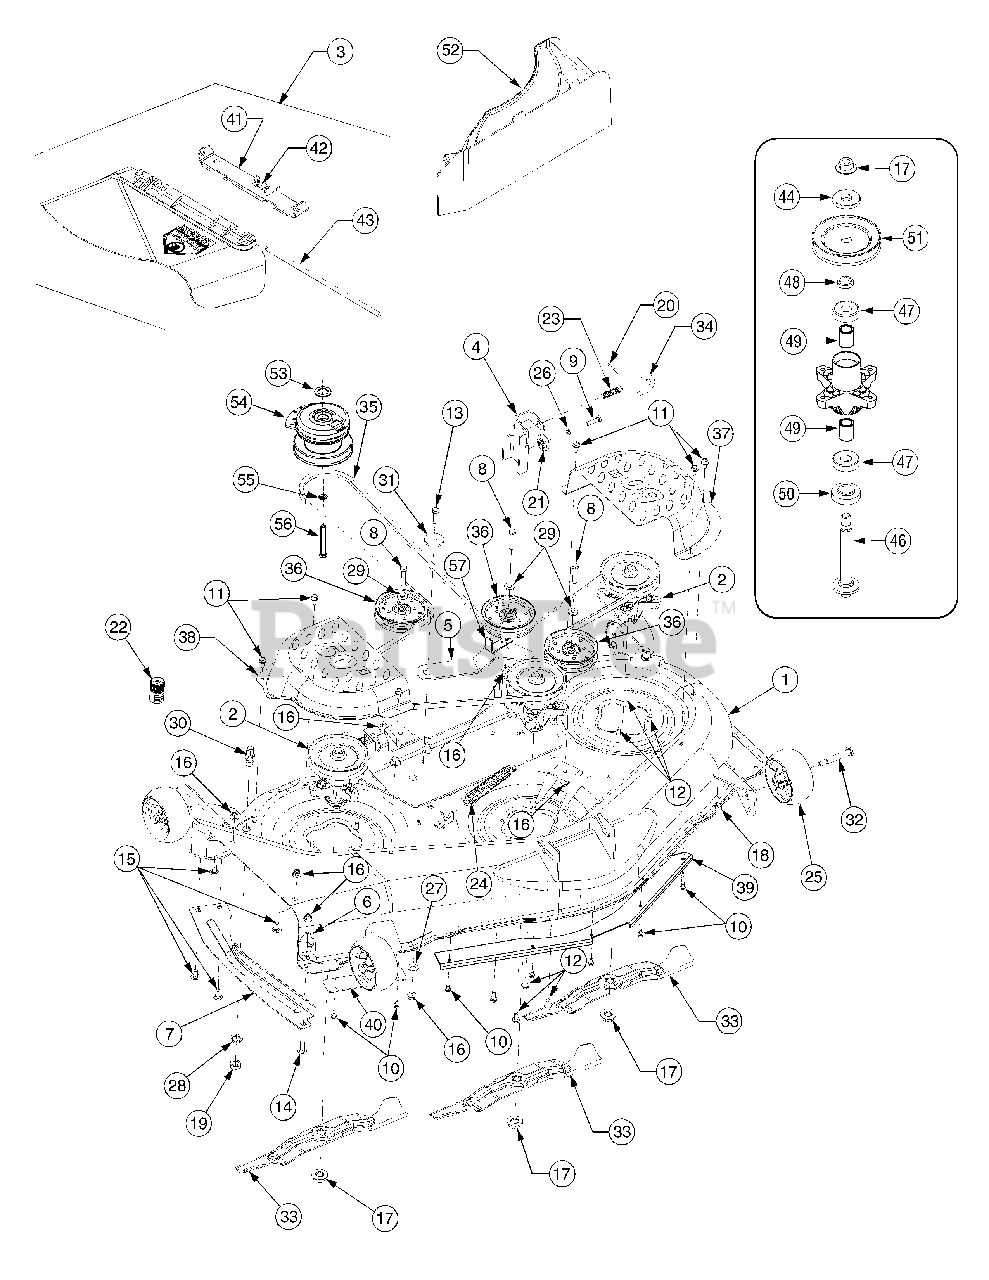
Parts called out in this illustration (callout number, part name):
2	Spindle Assembly
3	Discharge Chute Ass’y
7	Guard, Finger
8	Hex Screw 3/8-16 x 1.75
9	Hex Bolt 5/16-18 x 1.25
10	Hex Wash S-Tapp Screw 1/4-20 x .50
11	Hex Wash HD AB Screw 5/16-18 x .75
12	Hex Wash. Hd. Screw. 5/16-18 x .75 Lg.
13	Hex Bolt 3/8-16 x 1.25
14	Carriage Bolt 3/8-16 x 1" Lg. (Gr. 5)
15	Short Neck Carriage Bolt 3/8-16 x .75
16	Flange Lock-Nut 3/8-16 Gr. F Nylon
17	Hex Flange Nut 5/8-18
18	Hex. Flanged L-Nut 3/8-16 Gr. F
19	Hex Nut M16-1.5 DIN 936
20	Cotter Pin 1/8" Dia x 1.25
21	Deck Adjustment Gear
22	Water Nozzle Adaptor
23	Comp. Spring .531 OD x 1.75 Lg.
24	Extension Spring .94 OD x 6.74
25	Deck Wheel 5.0
26	L-Wash 5/16 ID
27	Cupped Washer .45 x 1.0 x .062
28	L-Washer Internal
29	Flat Washer .38 x .93 x .11
30	Port, Water
31	Shoulder Spacer .884 x .190
32	Shoulder Screw, 1/2 Diameter x 2.5
33	Blade 17.9" Lg.
34	Deck Release Pin
35	V-Belt Type A Sec x 134
36	Idler Pulley w/Flange 4.25 Dia
39	Deck Skirt Center
41	Chute Mounting Bracket
42	Torsion Spring
43	Hinge Pin
44	Flat Washer .76 ID x 1.5 OD x .12
46	Spindle Shaft 5.75 Lg.
47	Ball Bearing 20 x 47 x 14:6204:DS
48	Spacer .79 x 1.25 x .175
49	Spacer .080 x 1.10 x 1.322" Lg.
50	Spacer .79 x 1.82 x .55
51	V-Type Pulley, 5.29
52	Mulching Plug (optional)
53	Flat Washer 1.03 x 1.620 x .095
54	Electric PTO Clutch
55	Lockwasher 7/17
56	Hex Hd Cap Screw. 7/16-20 x 3.50
